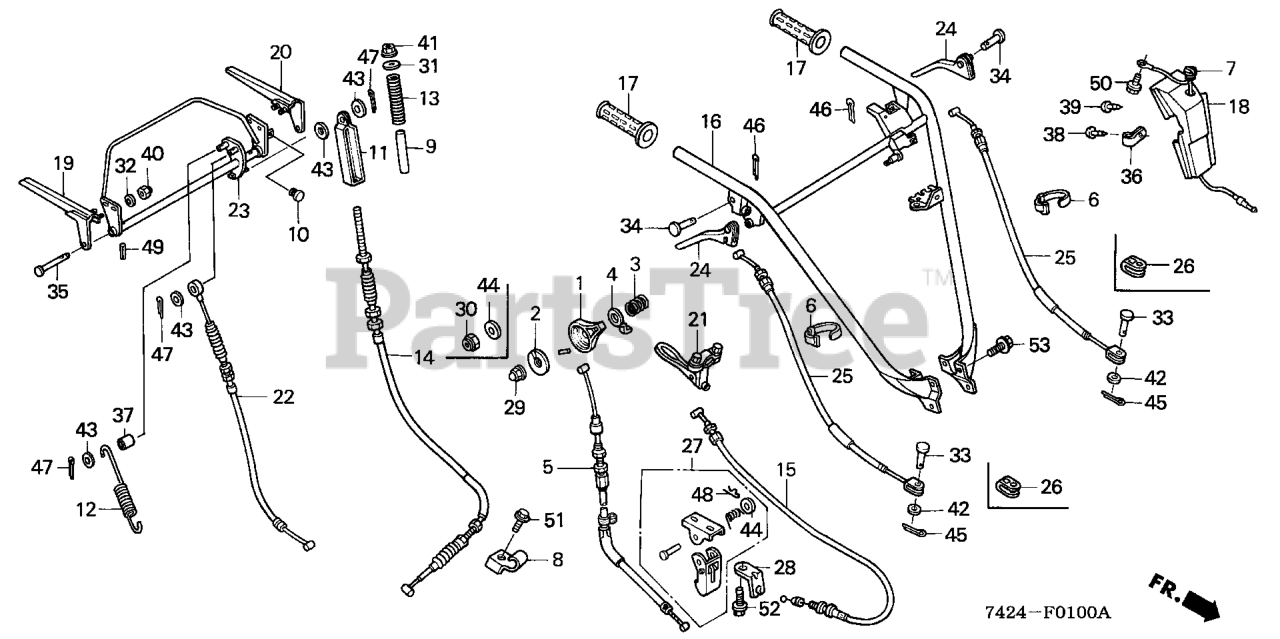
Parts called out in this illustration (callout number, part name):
1	LEVER, THROTTLE
2	PLATE, THROTTLE LEVER
3	SPRING, THROTTLE LEVER
4	SEAT, SPRING
5	CABLE, THROTTLE
6	BAND, CABLE
7	SWITCH ASSY., ENGINE STOP
8	HOLDER, BRAKE CABLE
9	COLLAR, BRAKE SPRING
10	RUBBER, STOPPER
11	HOLDER, BRAKE SPRING
12	SPRING, BRAKE RETURN
13	SPRING, BRAKE LOAD SETTING
14	CABLE, BRAKE
15	CABLE, CARRIER LOCK
16	PIPE, HANDLE
17	GRIP, HANDLE
18	COVER, CONTROL *NH105* (MAT BLACK)
19	LEVER, R. CLUTCH
19	LEVER,R CLUTCH
20	LEVER, L. CLUTCH
20	LEVER,L CLUTCH
21	LEVER, CARRIER LOCK
22	CABLE, CLUTCH
23	SHAFT, CLUTCH LEVER
24	LEVER, SIDE CLUTCH
25	CABLE, SIDE CLUTCH
26	JOINT, SIDE CLUTCH WIRE
27	LOCK ASSY., CARRIER
28	STAY, CABLE
30	NUT, U (6MM)
31	WASHER, PLAIN (6MM)
32	WASHER (6MM)
33	PIN, SIDE CLUTCH ARM
34	PIN, SIDE CLUTCH LEVER
35	PIN, CLUTCH LEVER
36	CLIP, WIRE HARNESS (6.3MM)
37	COLLAR, CLUTCH LEVER
38	SCREW, TAPPING (4X8)
39	SCREW, TAPPING (5X12)
40	NUT, CAP (6MM)
41	NUT, FLANGE (6MM)
42	WASHER, PLAIN (6MM)
43	WASHER, PLAIN (10MM)
44	WASHER, PLAIN (10MM)
45	PIN, COTTER (2.0X12)
46	PIN, COTTER (2.0X22)
46	PIN, COTTER (2.0X35)
47	PIN, COTTER (2.5X22)
48	PIN, LOCK (10MM)
49	PIN, SPRING (5X18)
50	BOLT, FLANGE (6X10)
51	BOLT, FLANGE (6X14)
52	BOLT, FLANGE (8X14)
53	BOLT, FLANGE (8X16) Use from Engine SN 1000016.
